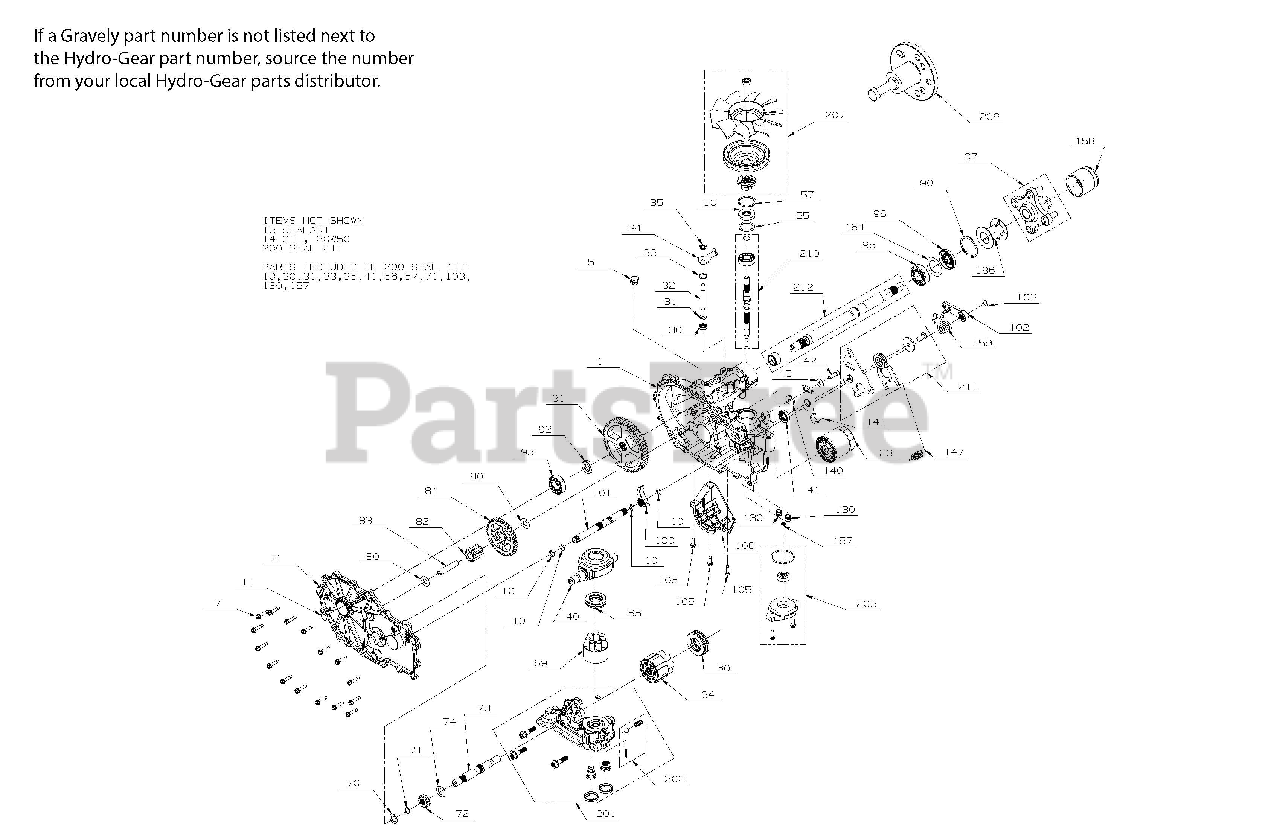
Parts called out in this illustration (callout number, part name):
1	KIT, MAIN HOUSING LH, CHARGE, CONTROL
2	KIT, SIDE COVER LH
7	SCREW,HEX WASHER 1/4-20X1.125
13	SEALANT TUBE 10.1OZ.
23	OIL FILTER, TRANSMISSION
30	SEAL, LIP .375X.75X.25
31	ROD, BYPASS
33	RING, RET .750
34	HG BYPASS ARM (52370)
35	RING, RTNG .
40	SWASHPLATE, TRUNNION
41	SEAL, LIP 18X32X7
55	WASHER 1.23X1.56X.04
56	SEAL, LIP 17X40X7
57	RING RETAINING INTERNAL
60	HG THRUST BEARING (51462)
64	HG 16CC CYLINDER BLOCK (71579)
65	BEARING. THRUST 30 X 52 X 13
69	KIT, BLOCK 7 PISTON
70	WASHER, .63 X 1.00 X .05 FLAT
71	RING, RET 62 EXT
73	SHAFT, MOTOR
74	WASHER .71 X 1.16 X .04
80	WASHER .75X1.5X.03
83	PIN, JACKSHAFT
90	SHAFT, JACK
93	KIT, BEARING
95	BEARING, BALL 25.4 X 52 X 15
96	SEAL, LIP
97	KIT, HUB 4 BOLT
100	PAWL, BRAKE
101	KIT, BRAKE SHAFT
102	HG ACTUATING KIT HANDLE
105	HFHCS 1/4-20X.75
106	HG FILTER GUARD LH (52247)
140	SPACER
141	ARM, NEUTRAL LEFT
142	SHCS 5/16-24X1 PATCH
147	RTN SPRING HG 51605
157	KIT, GEROTOR SEAL
158	CAP, AXLE
159	SPRING, TORSION
164	WASHER, 1.355 x 2.035 x .021 FLAT
200	KIT, SEAL
201	KIT, CENTER SECTION LH CHARGE
202	KIT, CHARGE RELIEF
203	KIT, CHARGE
207	KIT, FAN/PULLEY
209	HUB PULLER 4 BLT HYDGEAR 71459
210	INPUT SHAFT 2800 HYDGEAR 71442
211	TRN KIT HRDROGEAR P/N 71599
212	KIT, SHAFT, AXLE
